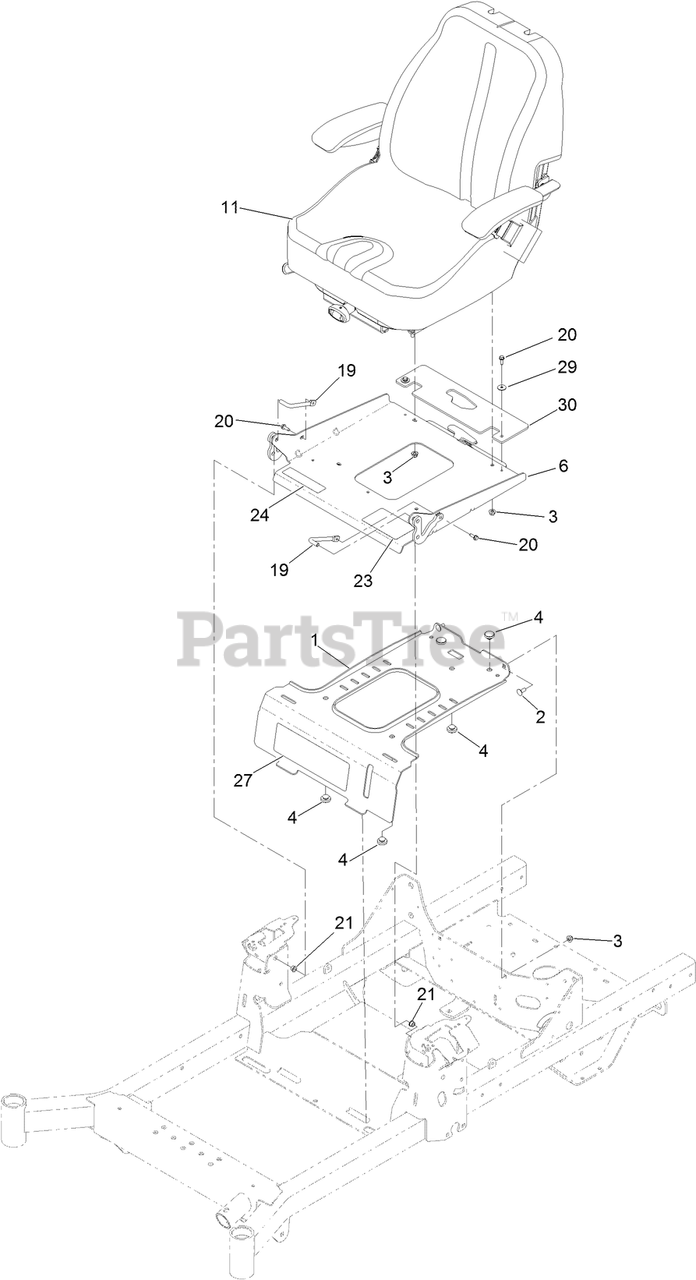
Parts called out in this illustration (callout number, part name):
1	PLATE-RETAINER, TANK
2	SCREW-CARR
3	NUT-HF, NI
4	BUMPER-SEAT
6	SEAT PAN AND LATCH ASM
11	SEAT ASM
19	PIN-PIVOT, SEAT
20	SCREW-HWH, THREAD ROLL
21	BUSHING-FLANGED
23	DECAL-AID, SERVICE
24	DECAL-LATCH, SEAT
29	WASHER
30	GUARD-SEAT, RUBBER
